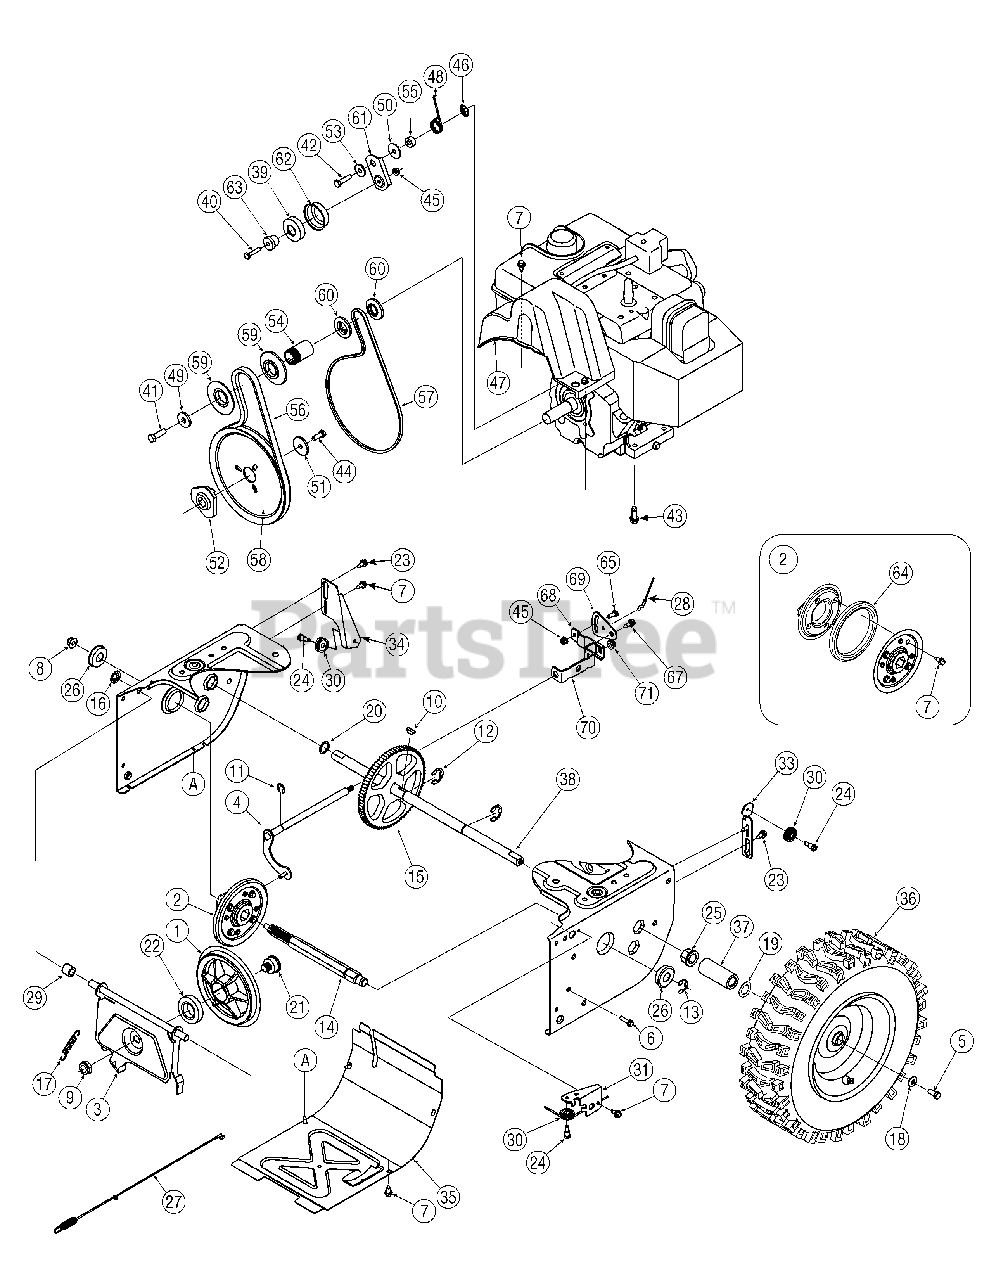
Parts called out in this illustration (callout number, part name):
1	Disc, Friction Wheel
2	Friction Wheel Assembly, 5.5 OD
4	Shift Assembly, Rod
5	Hex Screw, 5/16-24, .750, Gr5, Lock
6	Screw, 1/4-20, 1.000
7	Screw, 1/4-14 x .625
8	Nut, Flange Lock, 3/8-16, GrF, Nylon
9	Nut, Jam Lock, 5/8-18, Gr5, Nylon
10	Key, Hi Pro, 3/16 x 3/4 Dia.
11	E-ring, .500 Dia.
12	E-ring, Retaining, .875 Dia.
13	E-ring, .750 Dia.
14	Hex Shaft, .8125, 7-Tooth
15	Gear, 80-Tooth
16	Speed Nut, .500
17	Extension Spring
18	Washer, Bell, .340 x .872 x .060
19	Washer, Flat, .793 x 1.24 x .060
20	Washer, Flat, .75 x 1.00 x .060
21	Pin, Friction Disc
22	Ball Bearing, 30 x 55 x 13
23	Screw, Shoulder, .373 x .105, 1/4-20
24	Screw, 1/4-28, .375
25	Bearing, Hex Flange x .75 ID
26	Bearing, Ball, 17 x 40 x 12
27	Clutch Cable, Wheel, 44.95"
28	Clutch Cable, Auger, 47.23"
29	Spacer, .508 ID x .75 OD x .68
30	Roller, Cable
37	Spacer, 1.25 x .75 x 3.0
38	Axle, .75 x 22"
39	Ball Bearing
40	Hex Screw, 1/4-20, 1.25, Gr5
41	Hex Screw, 3/8-24, 1.25, Gr8
42	Hex Screw, 5/16-24, 1.25, Gr5, Lock
43	Screw, Sems, 3/8-16, 1.00
44	Hex Screw, 5/16-24, .875, Gr8, Lock
45	Nut, Flange Lock, 1/4-20, GrF, Nylon
46	Nut, Push-on, .25 Dia.
47	Cover, Belt
48	Spring, Torsion, .850 ID x .354
49	Washer, Flat, .406 x 1.25 x .157
50	Washer, Flat, .330 x 1.25 x .06
51	Washer, Flat, .34 x 1.50 x .150
52	Pulley, Adap, .75 Dia W/dd
53	Spacer, Shoulder
54	Spacer, .875 ID x 1.185 OD
55	Spacer, .340 x .750 x .360
56	Belt, Auger Drive
57	Belt, Wheel Drive
58	Pulley, Auger Drive, 8.1 x .5
59	Pulley, Half, V x 2.600 OD
60	Pulley, Half, 1/4-V x 1.5 OD
61	Idler Bracket, Wheel Drive
62	Sleeve, Bearing Idler
63	Spacer, Shoulder, .260 x .790 x .538
64	Rubber, Friction Wheel, 5.5 OD
65	Hex Screw, 1/4-20, .620, Gr5
66	Spring, Torsion, .750 ID x .968
67	Screw, Shoulder, .373 x .105, 1/4-20
68	Bracket, Shift Spacer
71	Nut, Flange Lock, 5/16-18, Nylon
